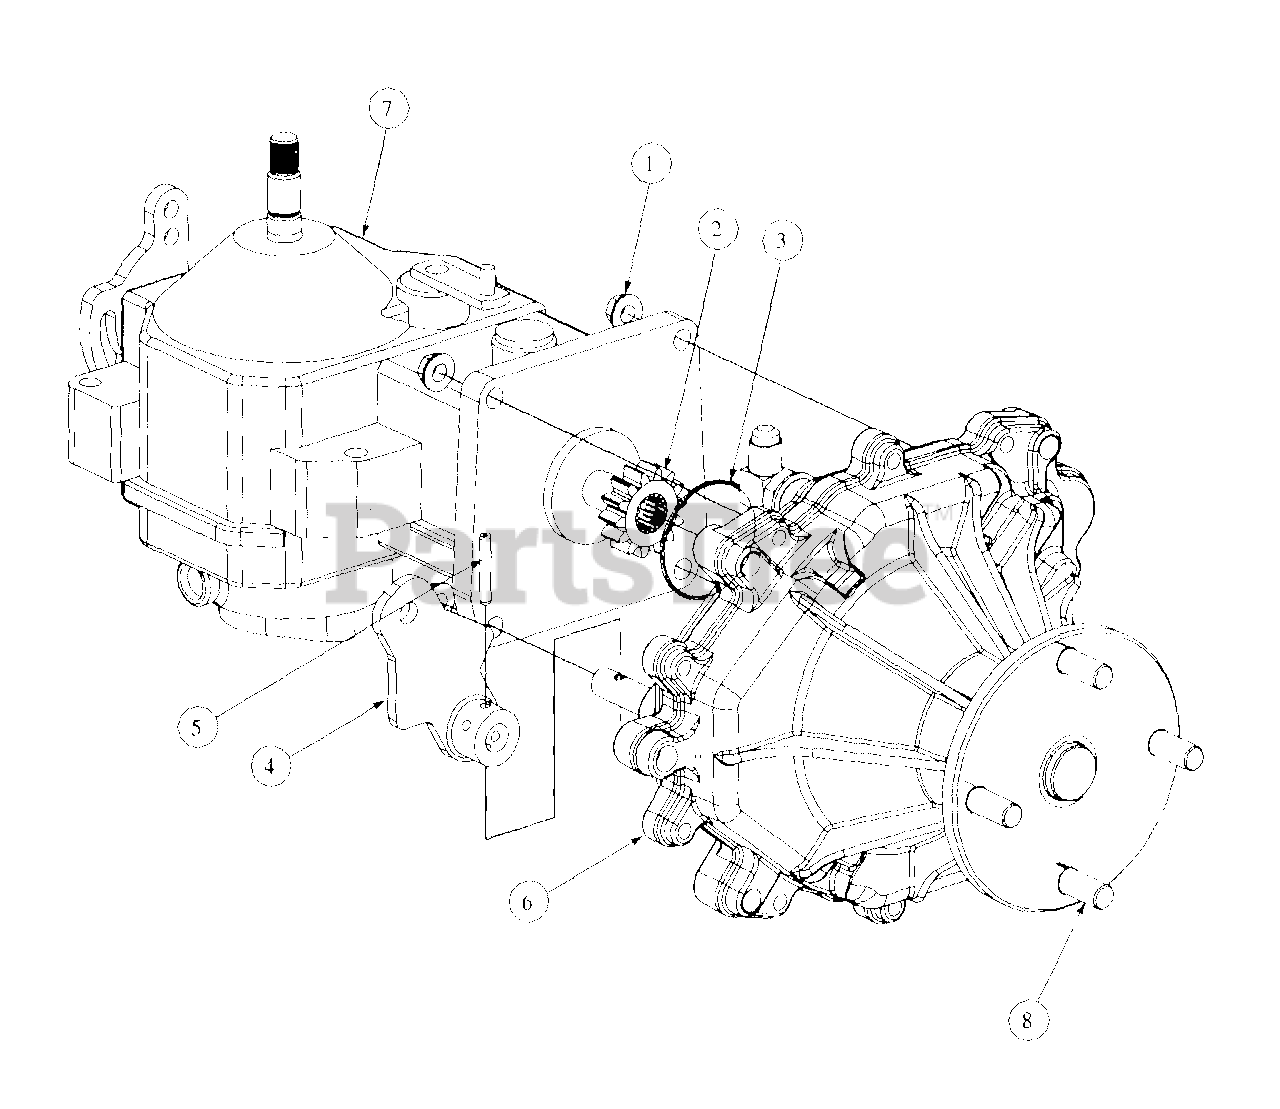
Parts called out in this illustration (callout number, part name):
1	Hex Flange, Lock Nut, 5/16-18
2	Gear, Spur, 14T
3	O-Ring, 2.00 x .070
4	Lever, Bracket, Park
5	Pin, Spirol, 3/16 x 1.25 HD
6	Transmission Assembly
7	Pump Kit, Right Hand
8	Rib Neck Studs, 7/16-14 X 1.6
